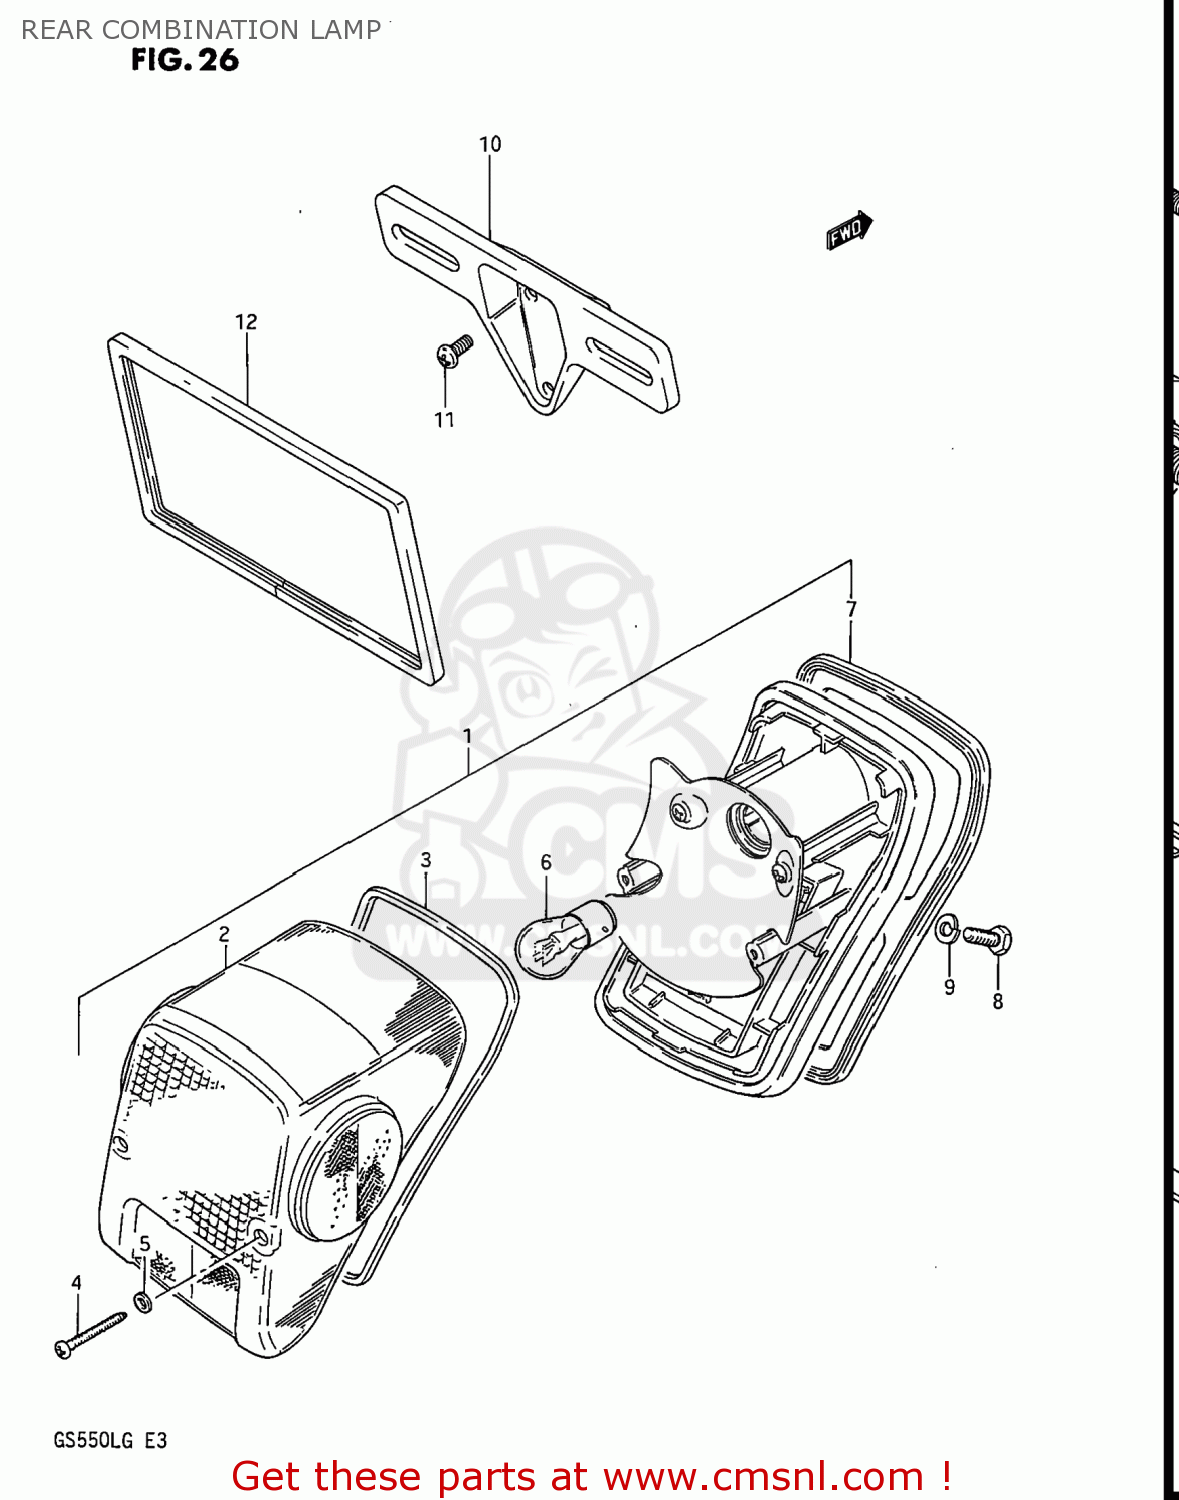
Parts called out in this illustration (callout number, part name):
1	LAMP ASSEMBLY,REAR COMBINATION
2	LENS
3	GASKET (NAS)
4	SCREW
5	GASKET (NAS)
6	BULB(12V23/8W,TOKAI DENSO)
7	CUSHION,REAR COMBINATION LAMP
8	BOLT
9	WASHER,LOCK
10	BRACKET,REAR LICENSE
11	SCREW
